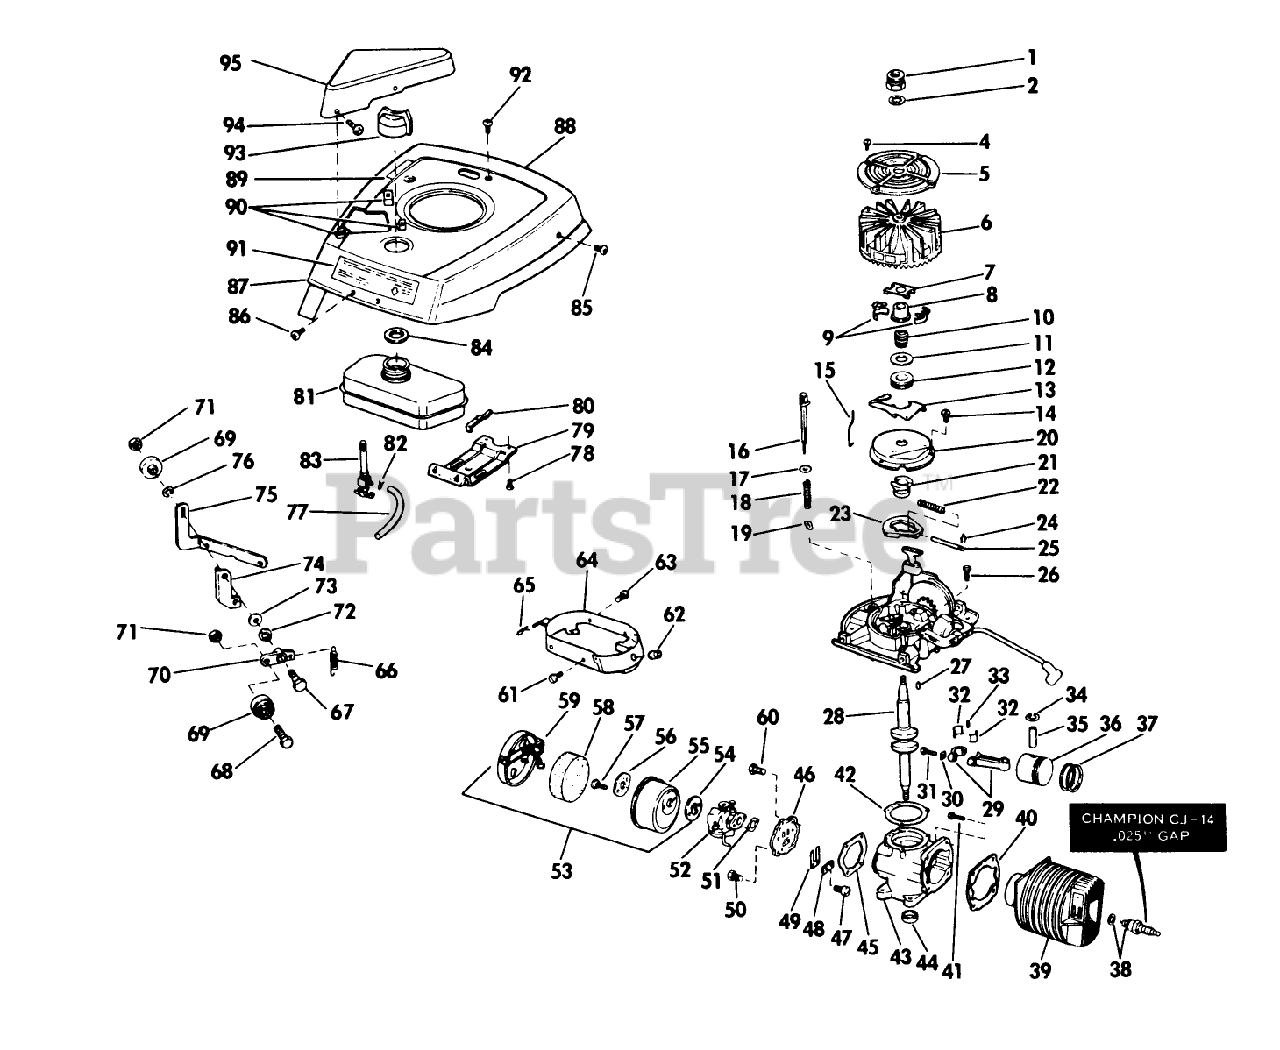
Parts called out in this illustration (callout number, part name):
4	SCREW F
6	FLYWHEEL S
8	COLLAR S
12	THRUST COLLAR S
13	LEVER-GOVERNOR S
14	SCREW S
18	SPRING S
20	DUST COVER S
21	SPARK ADV. S
22	SPARK ADV. SPRING S
23	FLYWEIGHT S
24	SPARK ADJ. SPRING
25	PIN,SPARK ADV. S
32	LINER ASM
34	RING-RETAINING
38	Spark Plug and Gasket
40	GASKET S
42	GASKET S
45	GASKET S
46	REED PLATE AY. S
48	PLATE-BACKUP, REED
50	SCREW S
51	GASKET S
54	GASKET S
57	SCREW S
58	AIR FIL.ELEM S
60	SCREW S
61	SCREW S
62	NUT-CLIP
69	IDLER PULLEY
77	GAS LINE
78	SCREW S
82	CLAMP - HOSE S
83	VALVE&SCREEN SM
85	SCREW S
91	Decal-Instructions
92	SCREW F
95	BELT COVER AY
